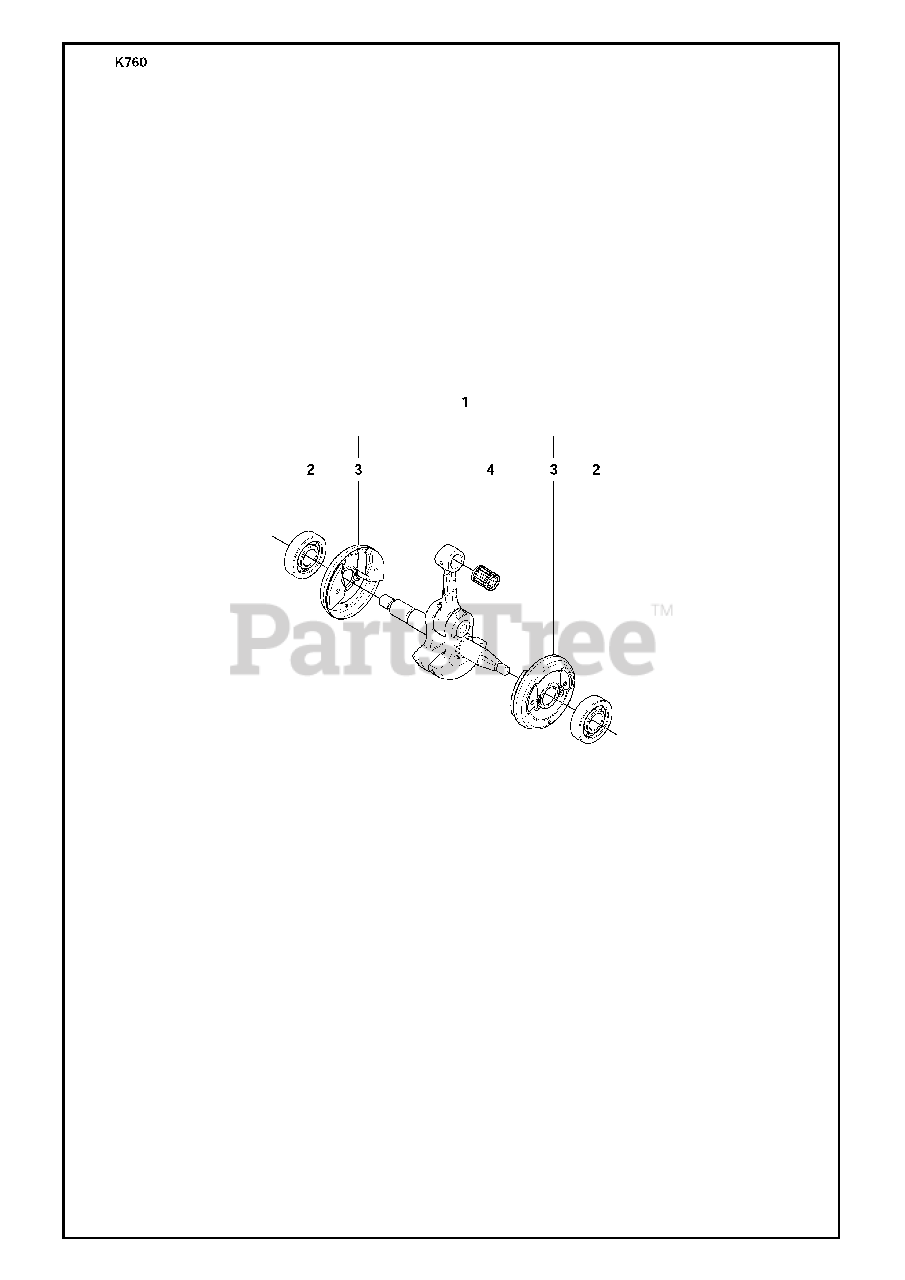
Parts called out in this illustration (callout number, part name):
1	Crankshaft Assy
2	Ball Bearing
4	Needle Bearing
